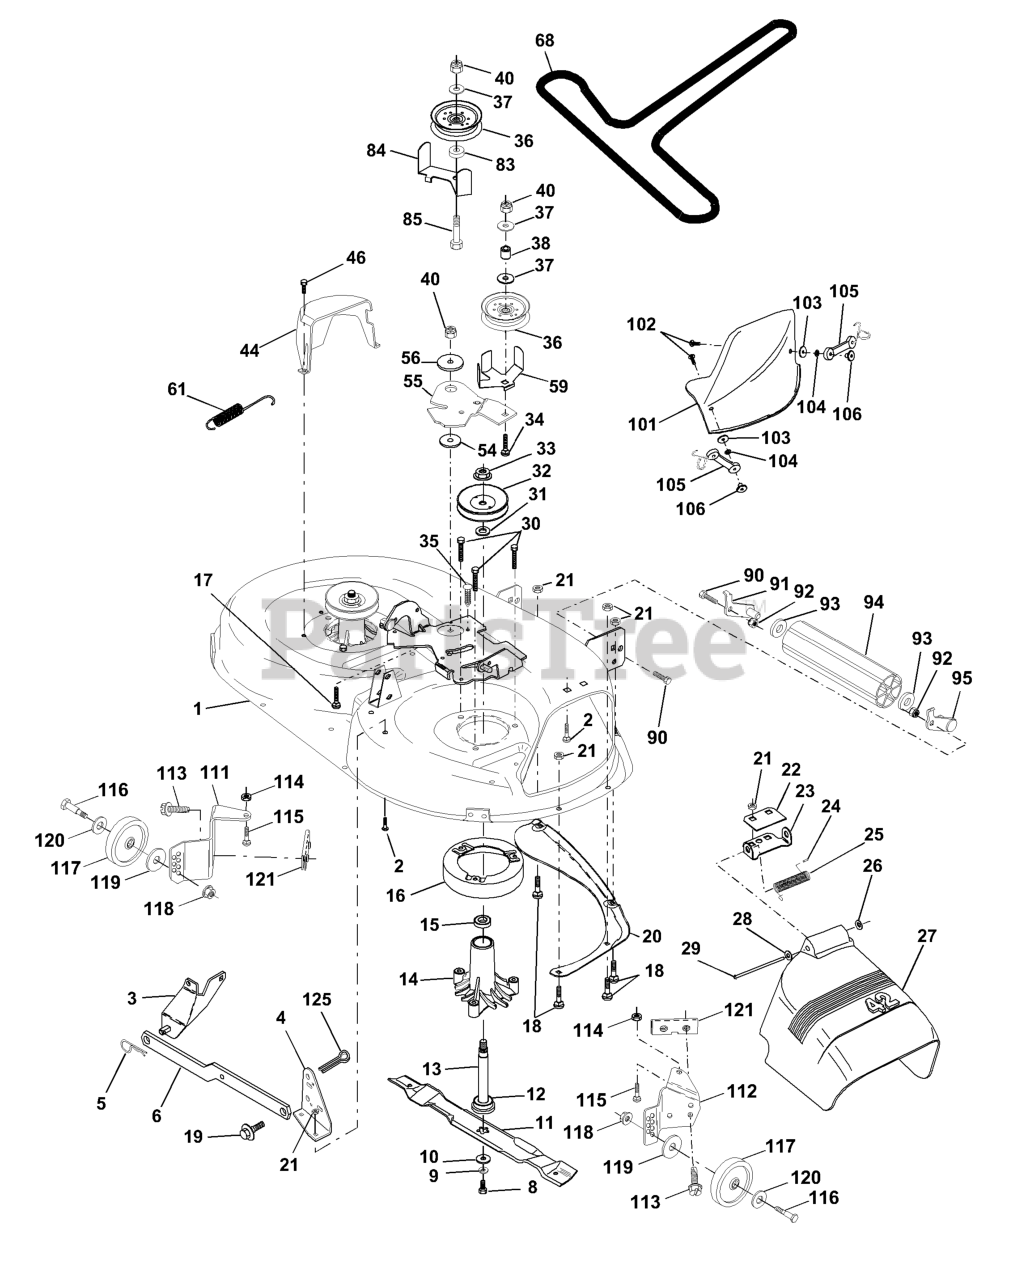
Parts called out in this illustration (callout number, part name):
1	DECK 42"
2	RP BOLT 5/16-18 X3/4 ZN/YEL GR
3	BRKT ASM SWAY BAR
4	BRKT DECK SW BAR
5	RETAINER-SPRNG RB
6	REAR SUSP ARM
8	BLADE BOLT
9	LOCKWASHER
10	WASHER.BLADE
11	BLADE.42".MULCH
12	BEARING.BALL.#6204.(MANDREL)
13	SHAFT ASM VENT
14	HOUSING.MANDREL.VENTED (MACHD)
16	STRIPPER
17	BOLT CARRIAGE
18	BOLT
19	BOLT SHD 5/16-18
20	BAFFLE
21	LOCKNUT
22	STIFFENER BRACKET
23	DEFLECTOR BRACKET
24	CAP-SLEEVE LT
25	SPRING TORSION
26	NUT PUSH M
27	SHIELD.DEFLECTOR.MOWER.42".BLK
28	Washer 11/32 X 5/8 X 16 Ga
29	ROD.HINGE
30	SCREW
31	WASHER
32	PULLEY/MANDREL
33	NUT
35	FASTENER.XMAS.TREE
36	FLAT IDLER PULLEY
37	WASHER
38	IDLER SPRING SPACER
44	GUARD MANDREL LH BLACK
46	SCREW.1/4-20X5/8
54	HARDENED WASHER
55	IDLER ARM
56	SPACER RETAINER
59	GUARD, BELT
61	SPRING EXTENSION
68	V-BELT TRIPATH
84	KEEPER BELT
85	BOLT
90	BOLT
91	BRACKET LH (A)
92	NUT
93	Washer 17/32 X 7/8 X 16 Ga
94	NOSE ROLLER
95	BRACKET RH (B)
101	COVER MULCH 42"
102	SCREW
104	LOCKWASHER #10
105	LATCH ASSEMBLY
106	WELDNUT
111	BRACKET
112	BRACKET
113	SCREW.THDROL.5/16-18X3/4.TTY
114	NUT
115	BOLT.CARR.5/16-18X1/2
116	BOLT M
117	WHEEL.GAUGE.BLK.4.93
118	LOCKNUT
119	WASHER.5/16.FLAT.STE.STD.
120	Washer 17/32 x 15/16 x 12 Ga.
121	BRACKET.EXTRUDED.GAGE.WHEEL
125	Cotter Pin
